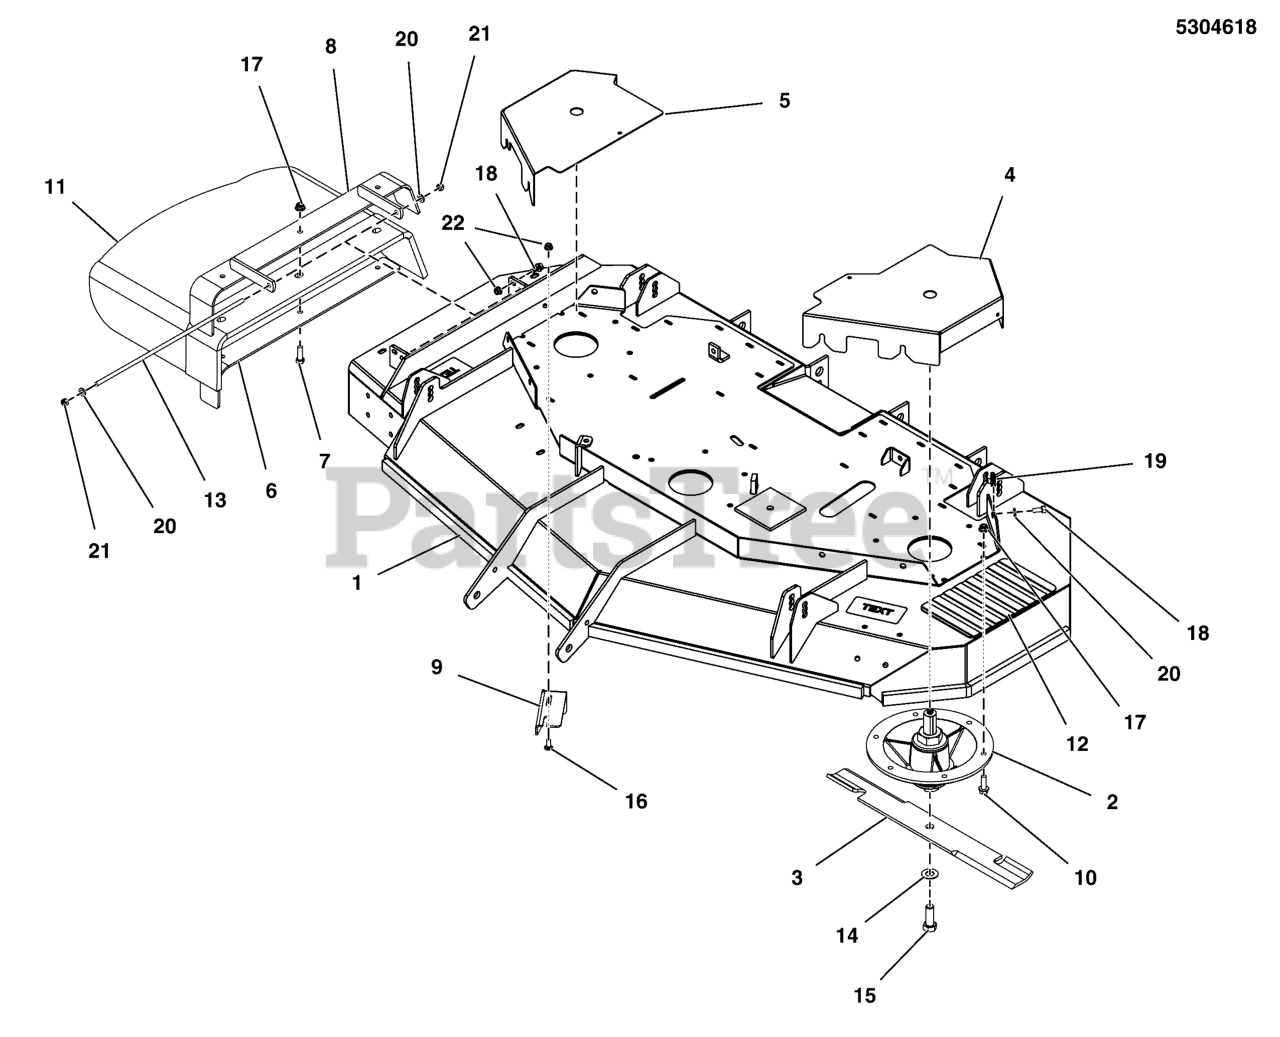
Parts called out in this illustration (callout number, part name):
1	DECK SHELL W/DECALS, 61, 3200Z (5414316B)
1	DECK SHELL W/DECALS, 61-3200E (5414316B)
1	DECK SHELL W/DECALS, 3200-61 (5422060B)
1	DECK SHELL W/DECALS, 3200-61E (5422060B)
2	SPINDLE ASSEMBLY
3	BLADE SET, 61 DECK (3)
4	GUARD, IS3200Z, LH 61" - RED
5	GUARD, MOWER DECK, IS3200-61, RH - RED
6	SUPPORT, DISCHARGE CHUTE - BLK
7	BOLT, 3/8-16 X 1-1/2, CARRIAGE, GD5, CZ
9	PLATE, DEFLECTOR - BLK
10	BOLT, 3/8-16 X 1-1/4, FLANGE, GD 5, CZ
11	CHUTE, RUBBER DISCHARGE (5104442)
12	SAFETY WALK, 9.75 X 6.00
13	ROD, MOUNT, CHUTE, 61, CZ
14	WASHER, BLADE BOLT, 9/16" F436, CZ
15	BOLT, 5/8-11 X 1-3/4 GD8
16	BOLT, 5/16-18 X 3/4, CARRIAGE, GD5, CZ
17	NUT, 3/8 - 16 HEX NYLOCK FLANGE
18	BOLT, 5/16-18 X 3/4 GD5
19	BODY CLIP, 5/16-18-7GA MATERIAL
20	WASHER, 5/16" SAE
21	NUT, 5/16-24 HEX NYLON LOCK
22	NUT, 5/16-18 HEX NYLOCK FLANGE NUT
